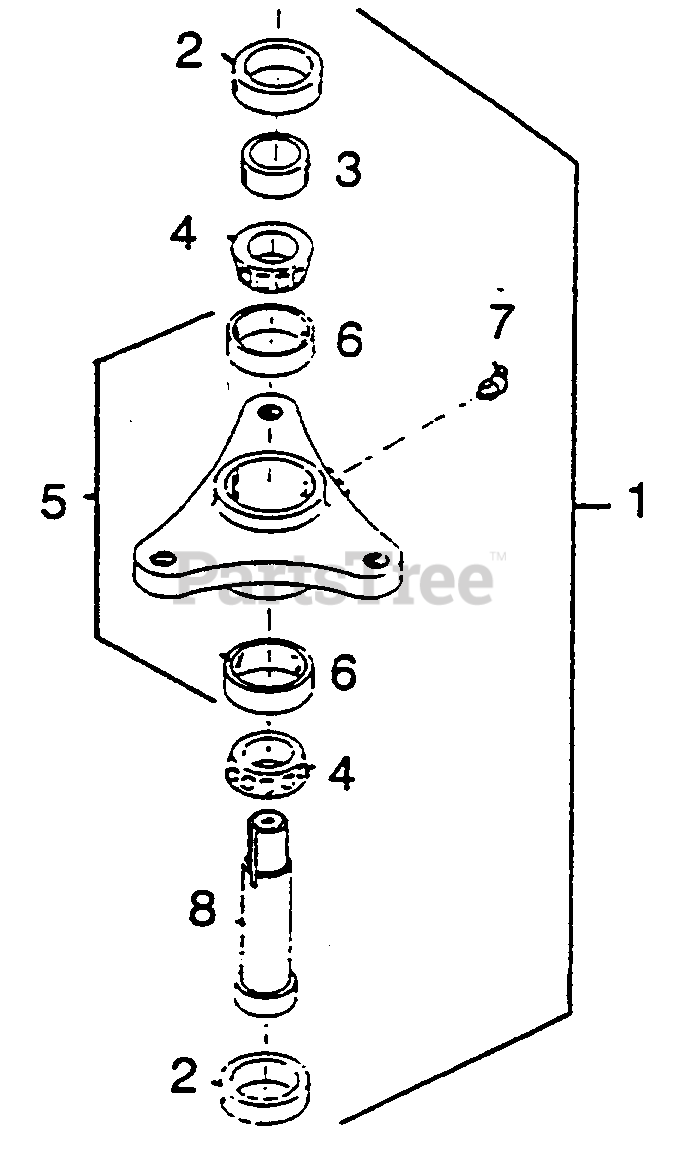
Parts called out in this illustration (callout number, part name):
1	CW Blade spindle assembly
2	Seal, 1.063 x 2.004 x .256
3	Sleeve, .84 x 1.06 x .310
4	Bearing cone #M12649
5	Spindle, housing with cups
6	Bearing Cup #M12610
7	45° 1/8 Pipe thread grease fitting
8	Spindle shaft, 1.06 x 3.88 - right hand threads
